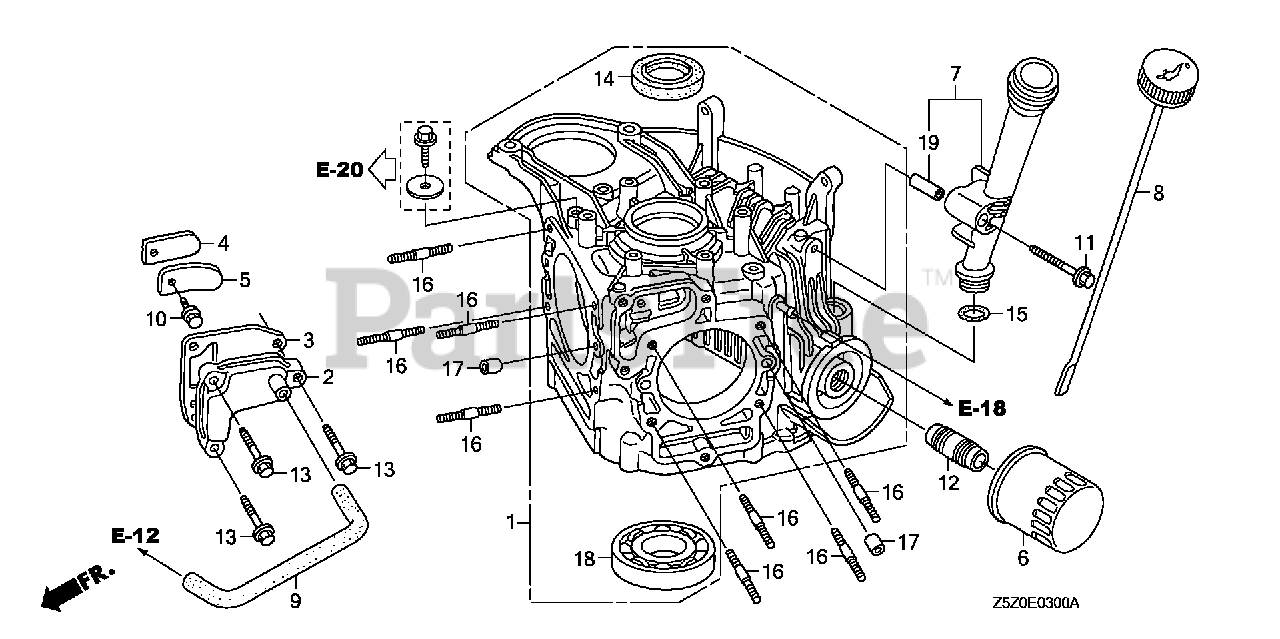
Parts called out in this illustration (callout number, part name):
1	CRANKCASE ASSY.
2	COVER, BREATHER
3	GASKET, BREATHER COVER
4	PLATE, VALVE
5	STOPPER, VALVE
7	EXTENSION, OIL FILLER
8	GAUGE, OIL LEVEL
9	TUBE, BREATHER
10	BOLT, FLANGE (5X10) Use from Engine SN 2327377.
11	BOLT, FLANGE (6X45)
13	BOLT, FLANGE (6X25) Use up to Engine SN 2056819.
14	OIL SEAL (35X52X8)
15	O-RING (22.5X2.2) Use from Engine SN 1257295.
16	BOLT 2, STUD (8X28)
17	PIN A, DOWEL (8X14)
18	BEARING, RADIAL BALL (6207)
19	COLLAR, EXTENSION
